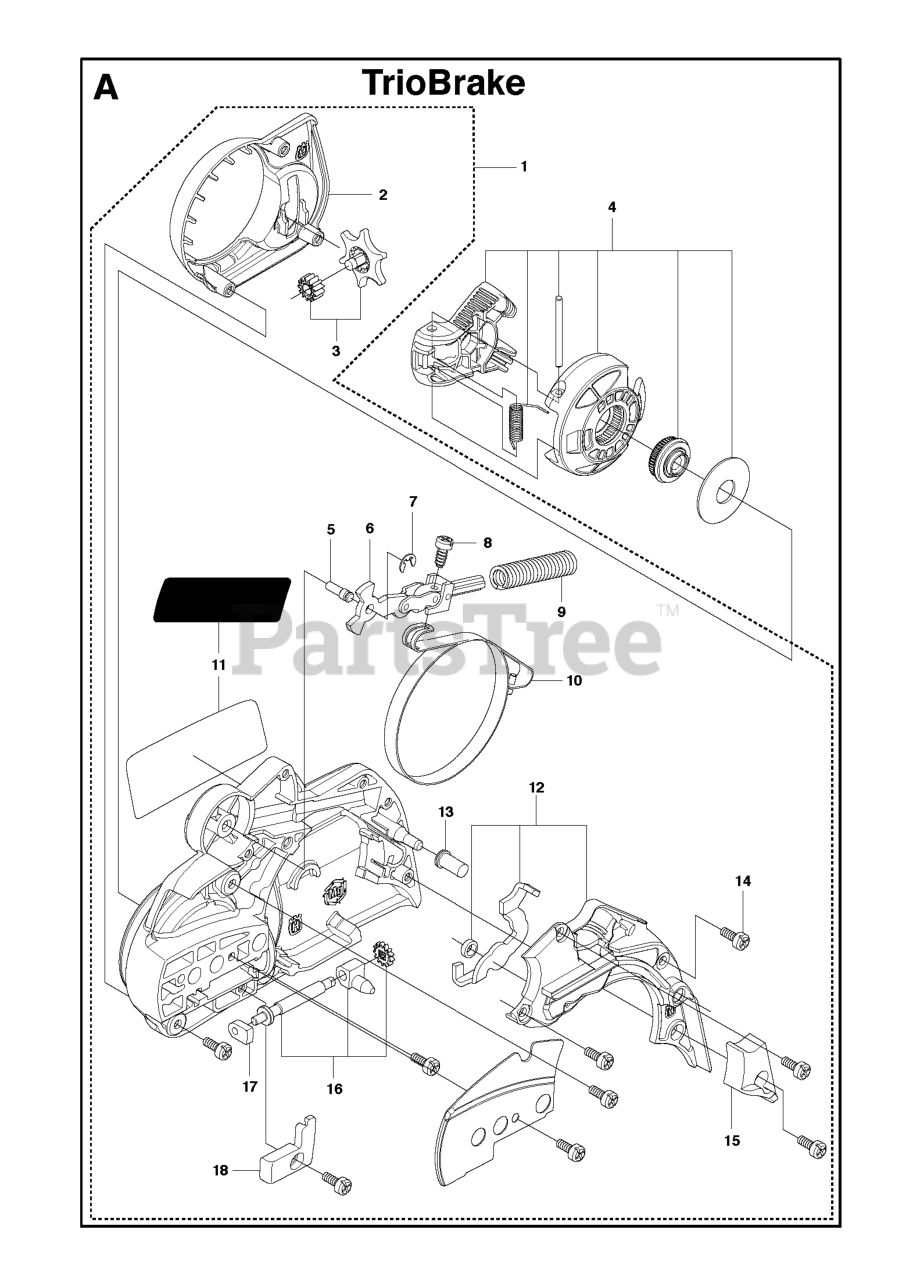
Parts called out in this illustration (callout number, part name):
1	CLUTCH COVER ASSY
2	HEAT SHIELD
3	CHAIN TENSIONER WHEEL, COMP.
4	KNOB, COMPLETE
9	BRAKE SPRING
10	BRAKE BAND ASSY
11	DECAL, CLUTCH HOUSING
15	WEAR PROTECTION
16	CHAIN TENSIONER SCREW
17	BEARING SLEEVE
